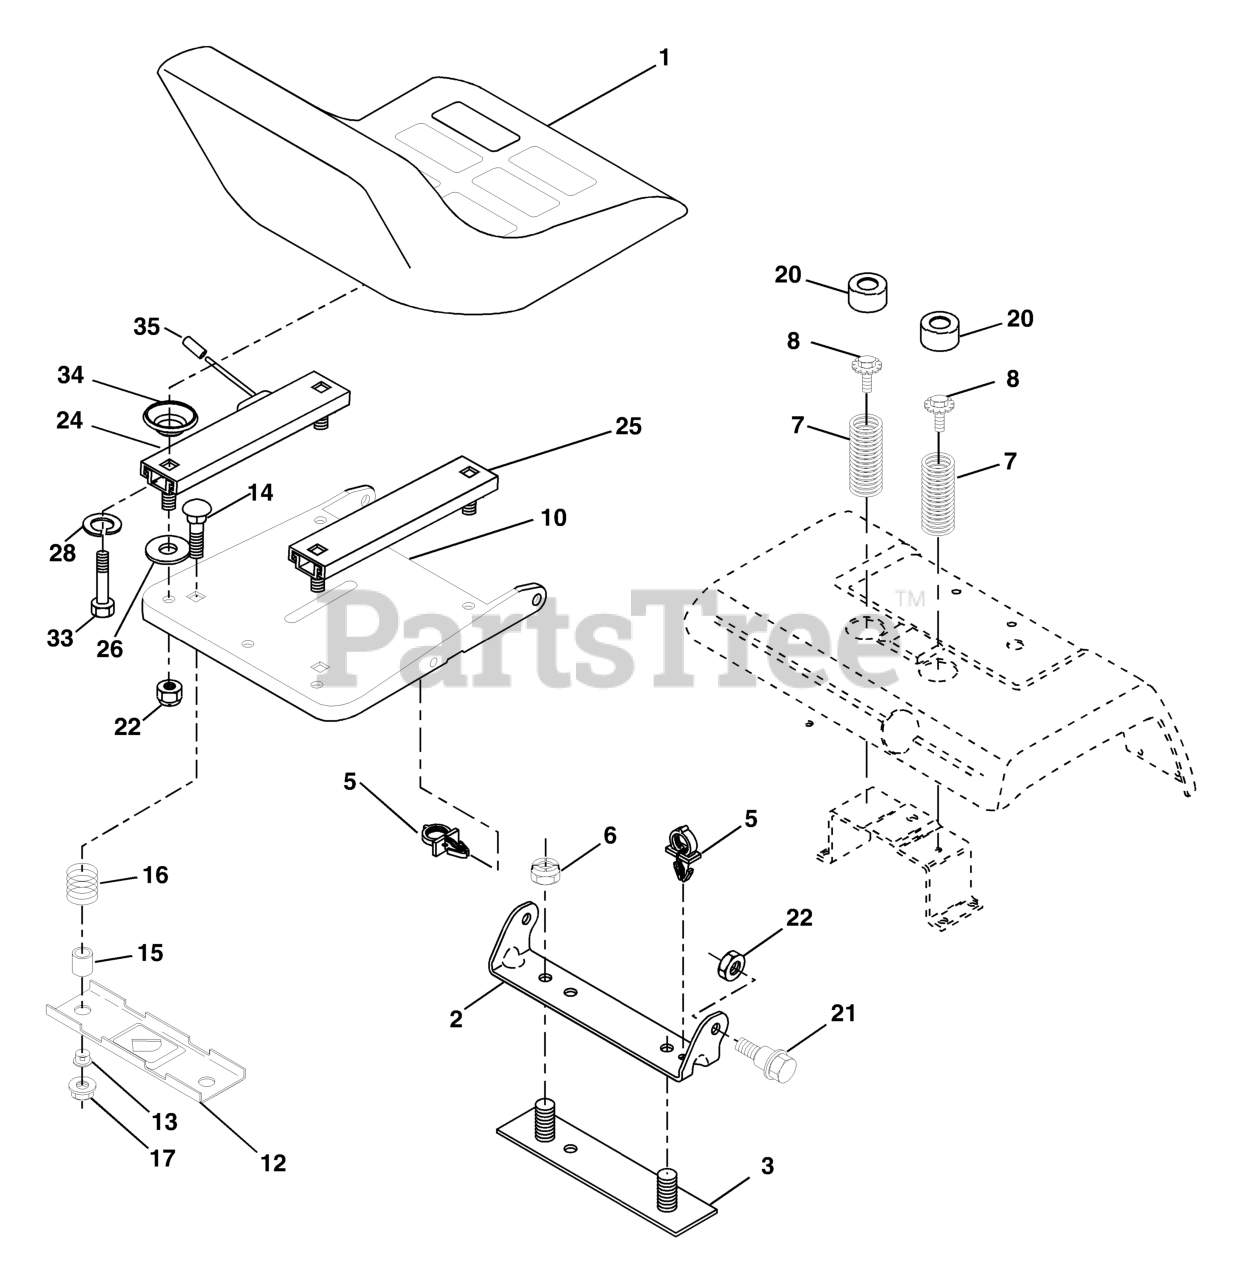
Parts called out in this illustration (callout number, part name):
1	SEAT
2	SEAT PIVOT BRKT
3	STRAP
6	NUT
7	SPRING COMPRESSION
8	BOLT.5/16-18UNCX3/4 W/SEMS.BLK
10	PAN, SEAT
12	BRKT SWITCH
14	BOLT.ROUND.HEAD.SQUARE.NECK
15	SPACER SPLIT
16	SPRING COMPRESSED
17	NUT T
20	CAP SPRING
21	BOLT.SHOULDER.5/16-18
22	NUT.71038.31-18.HEX.NYLOCK
24	TRACK SLIDE, SEAT(L)
25	TRACK SLIDE, SEAT(R)
26	WASHER
33	BOLT.FIN.HEX.5/16-18UNC X 1.00
35	CAP
